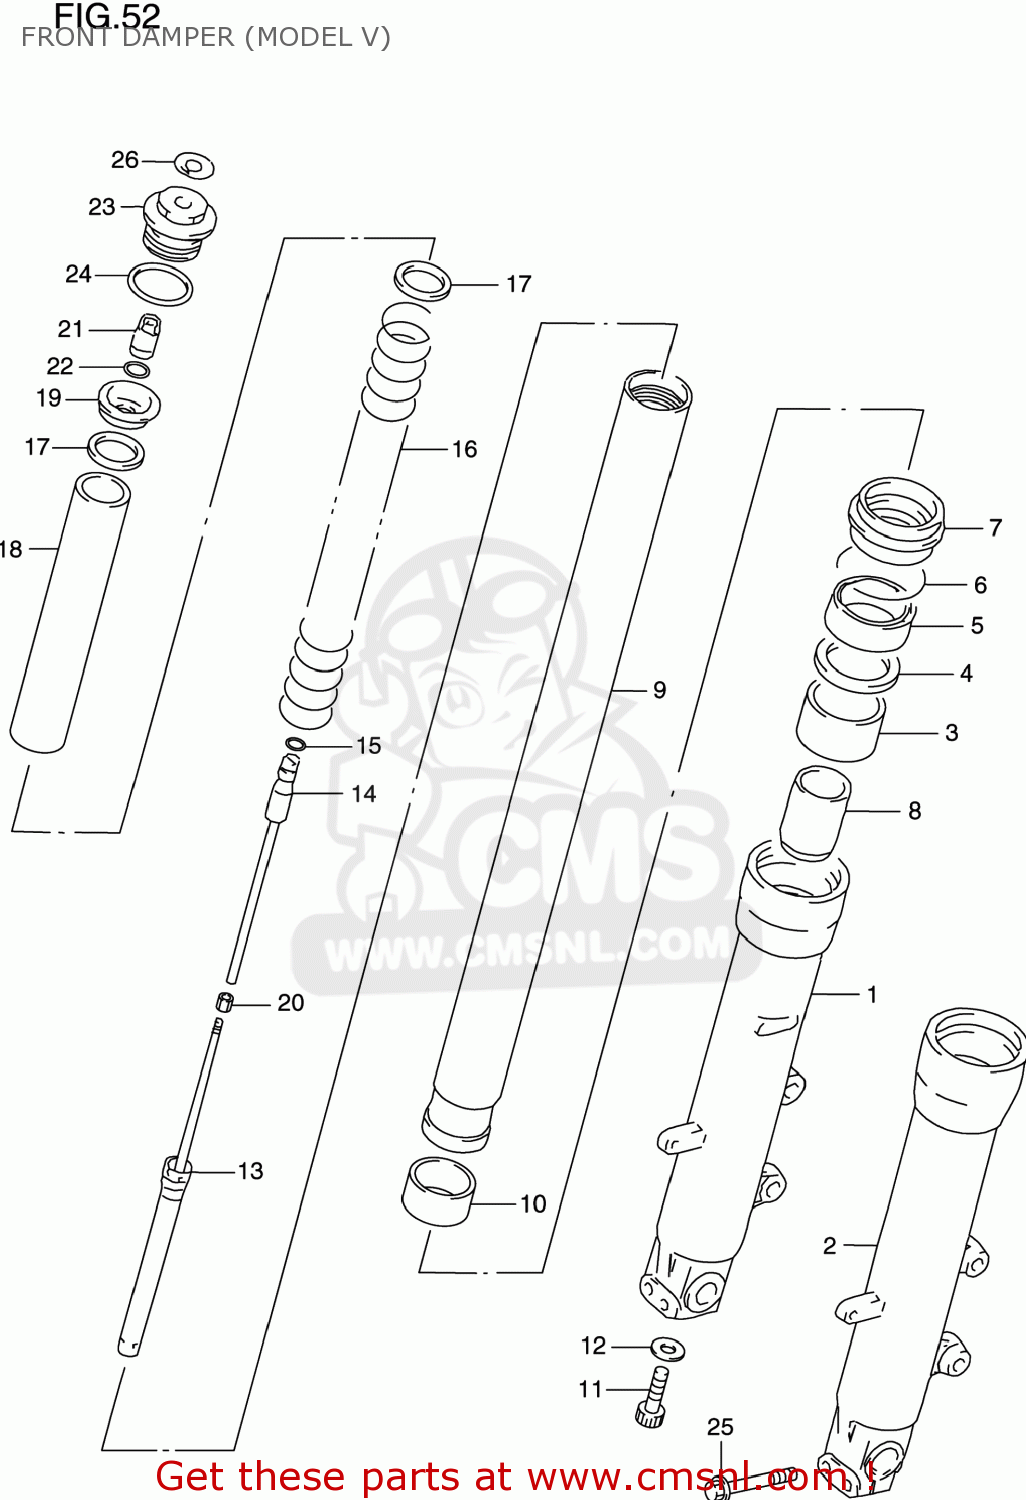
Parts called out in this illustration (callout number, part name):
1	TUBE,OUTER,R
2	TUBE,OUTER,LEFT
3	BUSH,GUIDE
4	SPACER,SEAL
5	SEAL,OIL
6	RING,OIL SEAL STOPPER
7	SEAL,DUST
8	PIECE,OIL LOCK
9	TUBE,INNER
10	BUSH,SLIDE
11	BOLT(8X27)
12	GASKET (NAS)
13	ROD,FR DAMPER
14	ROD,ADJUST
15	O RING(D:1.9,ID:3.8)
16	SPRING,FRONT
17	JOINT,SPRING
18	COLLAR,SPRING
19	SEAT,SPRING UPR
20	NUT
21	ADJUSTER,SPRING
22	O-RING (D:2.4 ID:13.8)
23	BOLT,FORK
24	O RING
25	BOLT
26	LABEL
